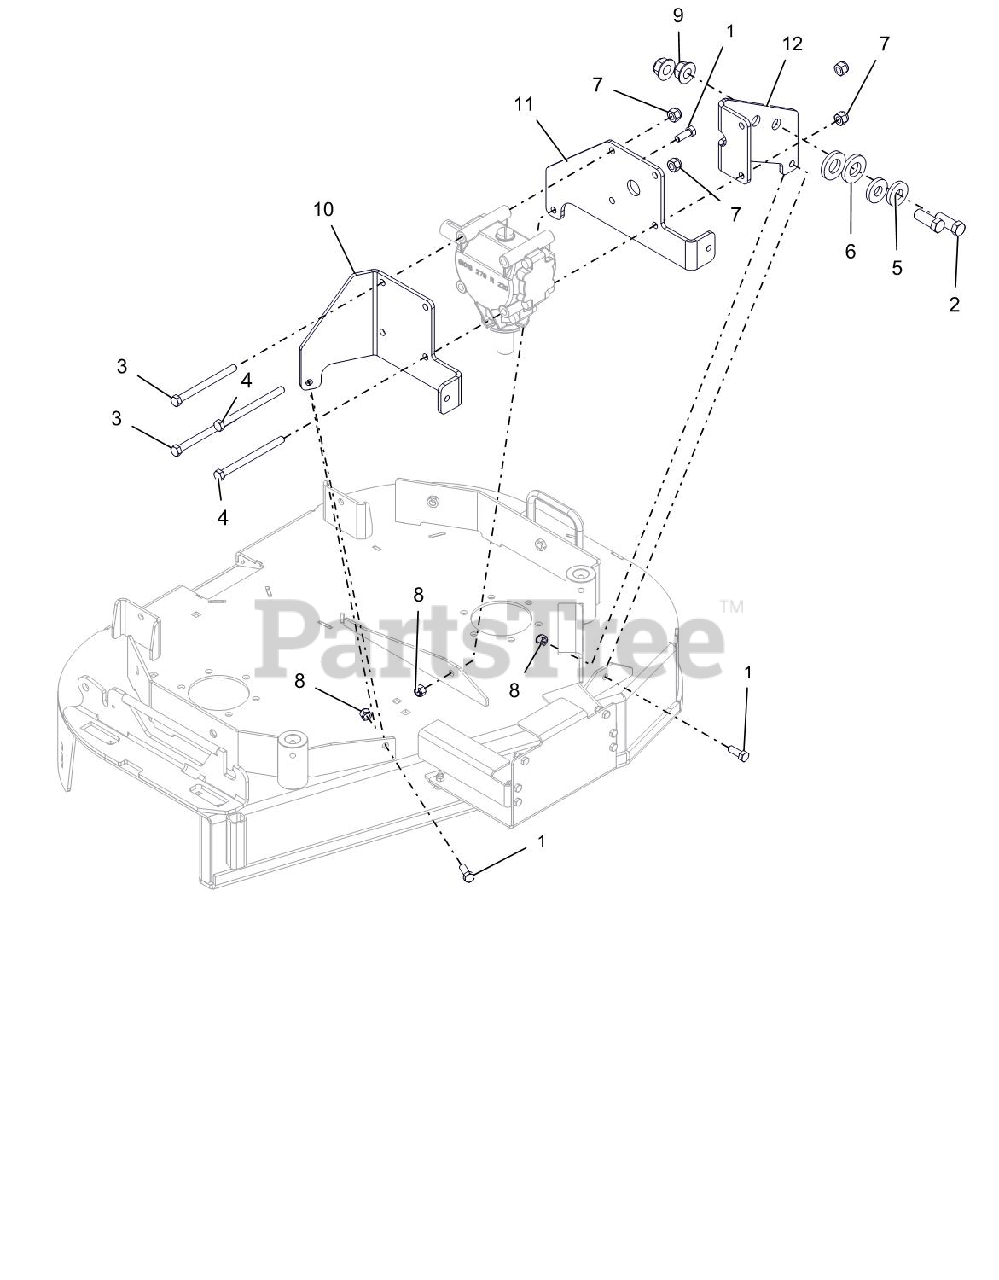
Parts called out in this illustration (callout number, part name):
1	BLT,HEX .38-16X1.00 G5 ZCC
2	BLT, HEX .62-11X1.50 G8 ZCC
3	BLT,HEX M10-1.5X120 G8.8 ZC120
4	BLT,HEX M10-1.5X130 G8.8 ZC120
5	WSHR,FLT .630X1.50X.25 ZCC
6	WSHR-FL-STL .905X1.75X.25 ZC12
7	NUT, LK-NYL M10-1.5 A2CL70 SS
8	NUT,NYL .38-16 G5 ZCC
9	NUT,NYL-FLG .63-11 GF ZCC
10	GEARBOX MNT RH
11	EAR, LH-INSIDE
